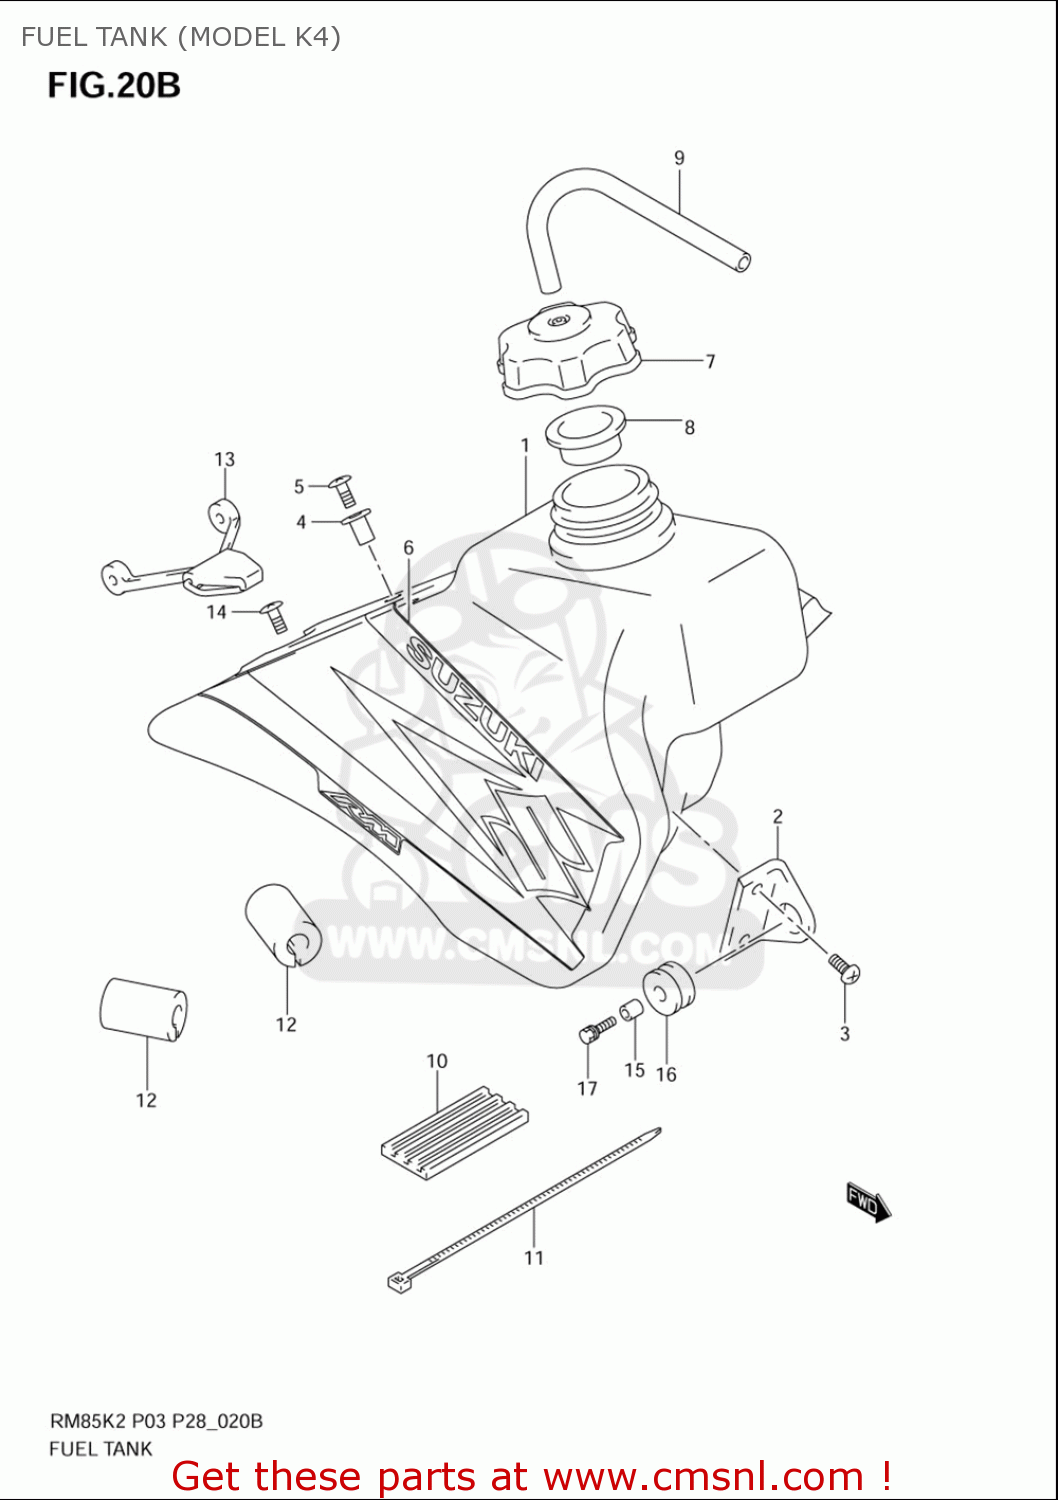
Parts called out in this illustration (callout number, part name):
1	TANK,FUEL(YELLOW)
2	BRACKET,FUEL TANK FR
3	SCREW
4	HOOK,SEAT FR
5	SCREW
6	TAPE SET,FUEL TANK
7	CAP,FUEL TANK FILLER
8	GASKET,CAP (NAS)
9	HOSE(5X8.2X600)
10	CUSHION,FUEL TANK UPR FR
11	CLAMP(L:250)
12	CUSHION,FUEL TANK UPR RR
13	BAND,FUEL TANK RR
14	SCREW(6X13.5)
15	SPACER(6.5X9X13.5)
16	CUSHION,MUFFLER
17	BOLT(6X35)
